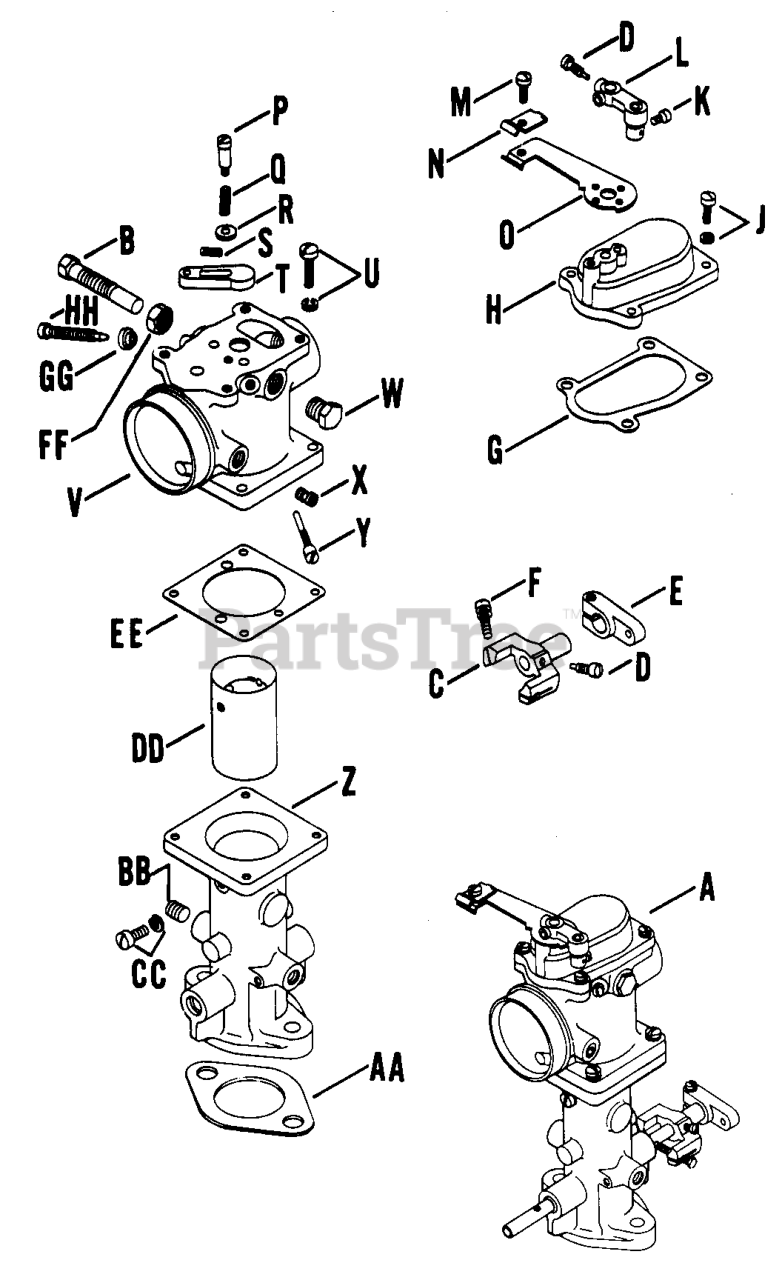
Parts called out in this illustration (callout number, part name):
B	Screw, fuel adjusting (Discontinued--Not Available)
C	Collar, throttle shaft
D	Screw, set
E	Lever, throttle
F	Screw, throttle stop adjusting
G	Gasket, cover plate
H	Plate, cover
K	Screw, choke swivel
L	Lever, choke
M	Screw, support clamp
N	Clamp, choke support
O	Support, choke
P	Screw, valve lever pivot
Q	Spring, pressure
R	Washer, spring retainer
S	Spring, latching
T	Lever, valve
U	Screw and split washer, air horn
V	Housing, air horn with nozzle
W	Plug, fuel adjusting
X	Screw, balance tube orifice
Y	Plug, starting adjusting
Z	Tube, throttle
BB	PLUG, PIPE DISCONTINUED
CC	Screw and split washer, venturi
DD	Venturi #30
EE	Gasket, air horn
FF	Locknut, fuel adjusting
GG	Locknut, starting adjusting
HH	Screw, starting adjusting
